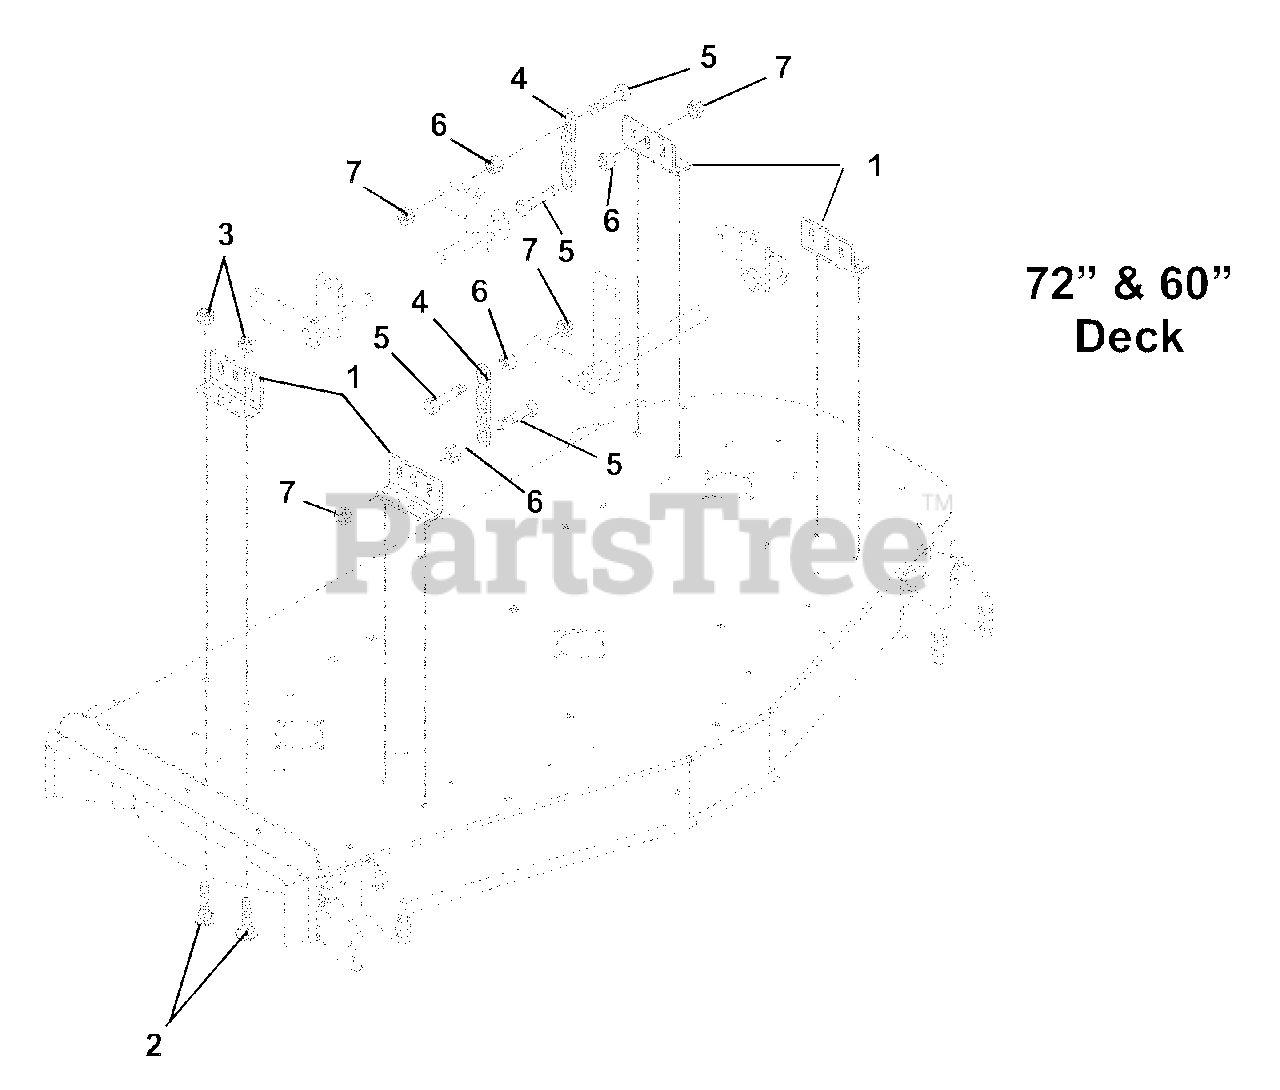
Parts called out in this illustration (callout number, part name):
1	Bracket, Mower Mounting
2	Bolt-Round Head Square Neck .38-16 x 1.00 Grade 2
3	Nut-Locking-Top-Flange .38-16
4	Chain, Link
5	Bolt-Hex M12-1.75 Grade 5
6	Nut, Spin Lock Flange M12-1.75
7	Nut-Locking-Top-Flange M12-1.75
